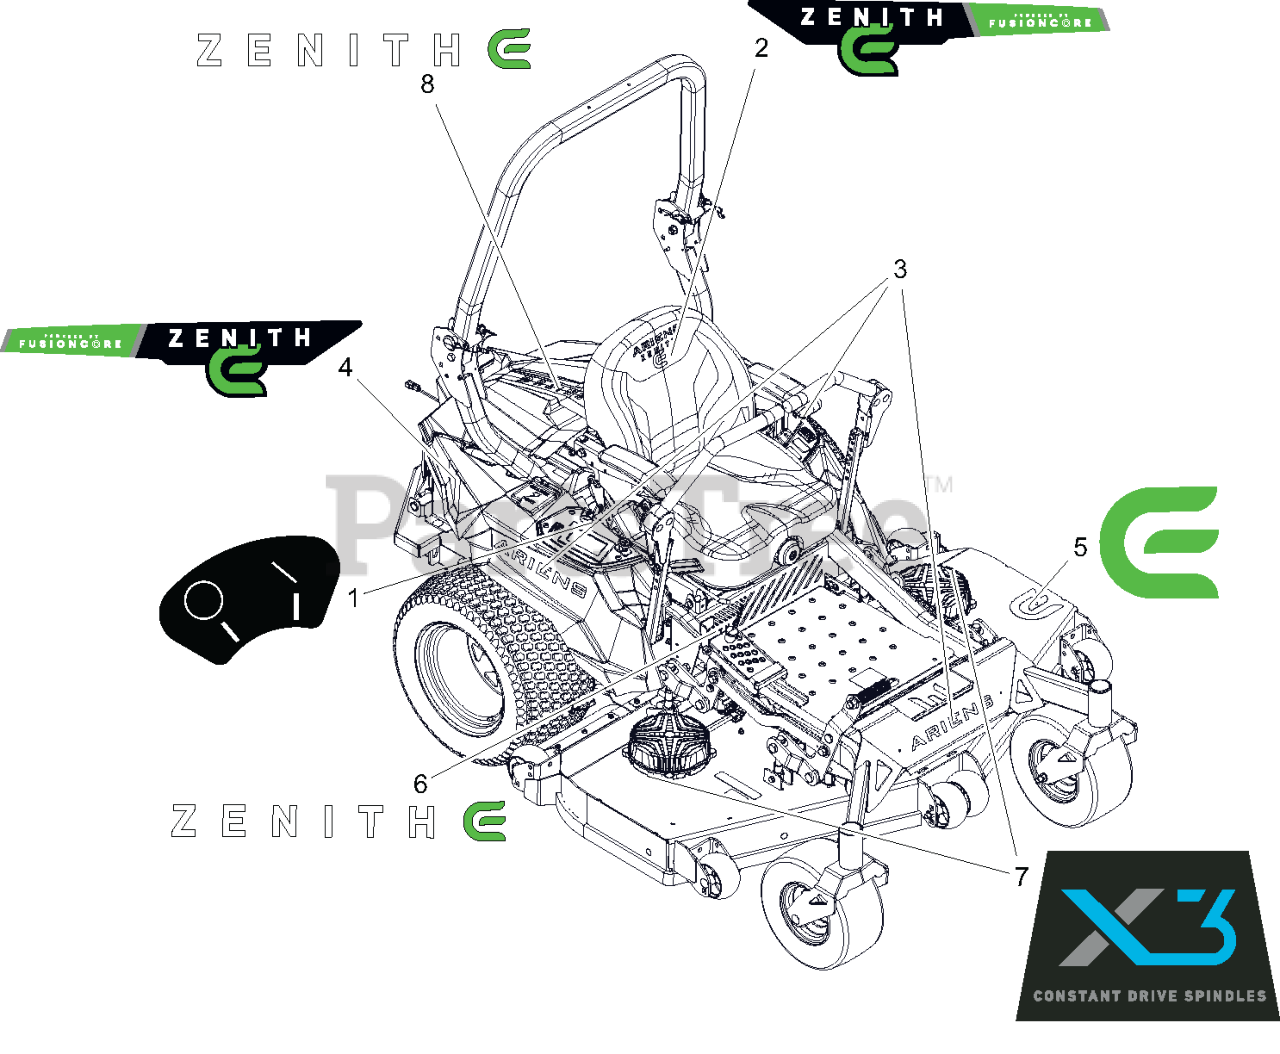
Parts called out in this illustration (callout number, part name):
1	DECAL, KEY SWITCH - 2 POS
2	DECAL, FENDER - ZENITH LH
3	DECAL, ARIENS - 12.0"
4	DECAL, FENDER - ZENITH RH
5	DECAL, ZENITH - E
6	DECAL, KICKPLATE - ZENITH
7	DECAL, DECK MOTOR
8	DECAL, HOOD - ZENITH
